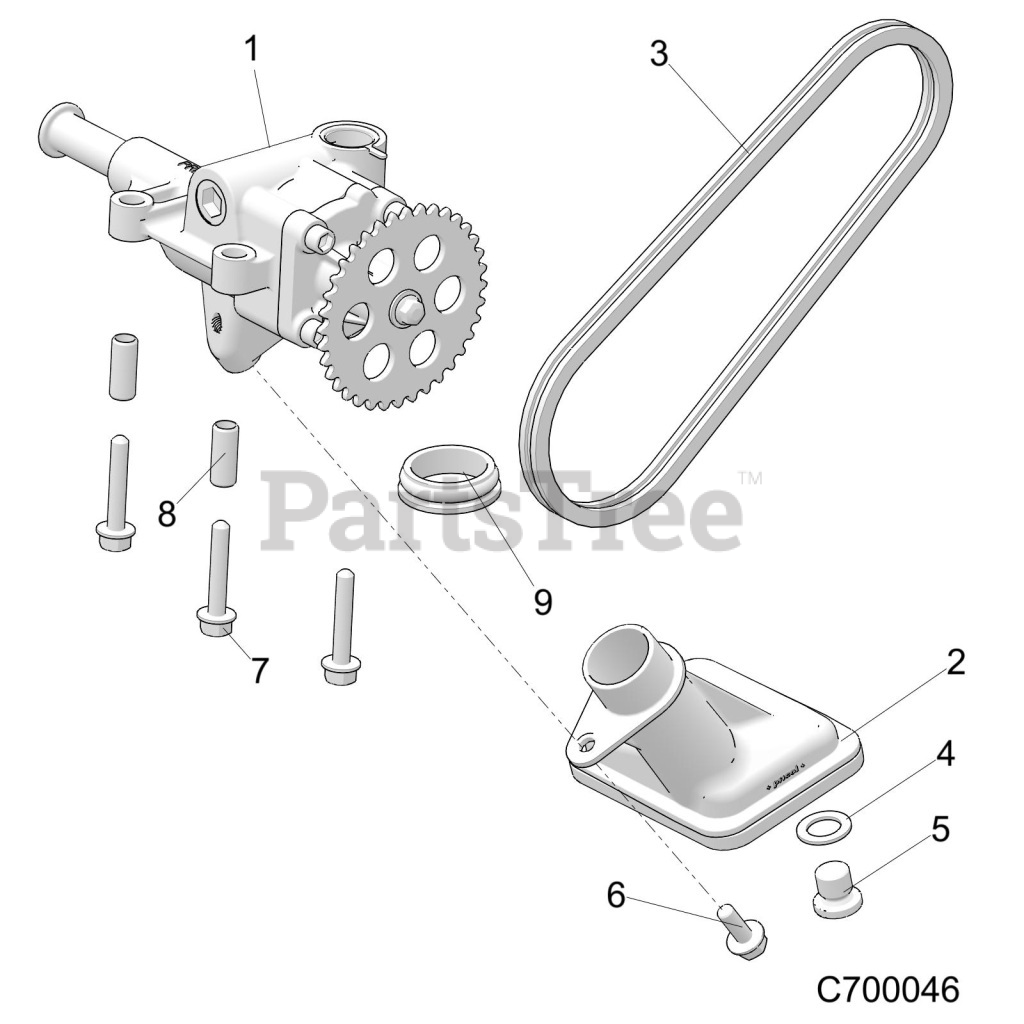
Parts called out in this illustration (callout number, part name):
1	ASM-PUMP,OIL,WET SUMP
2	PICK UP-OIL
3	CHAIN-OIL PUMP DRIVE,G-90
4	WASHER-19X12X1.3-COPPER (10)
5	PLUG-SOCKET,M12X1.5 DIN 908A
6	SCR-HXFL-M6X1.0X16 8.8 ZYL NYL
7	SCR-M6X1.0X35,HX/FL-Y/D
8	DOWEL-HOLLOW,OIL PUMP
9	SEAL, PICKUP
